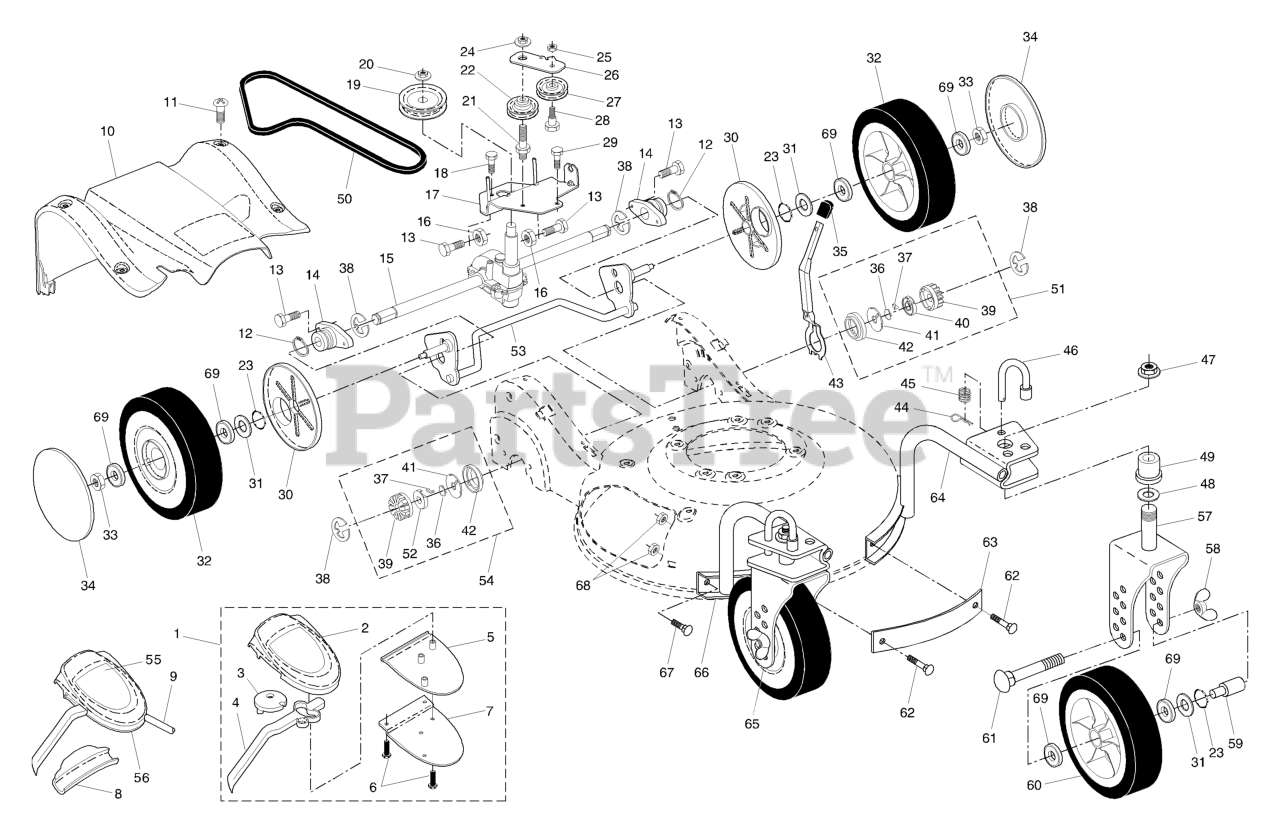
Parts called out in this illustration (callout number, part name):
1	EZ WALK CONTROL
2	COVER, DRIVE CONTROL, TOP
3	PULLEY.CAM.DRIVE.CONTROL.HV
4	LEVER, DRIVE CONTROL
5	COVER, DRIVE CONTROL BOTTOM
6	SCREW, PHILLIPS HEAD 10 X 5/8
7	BRACKET, DRIVE CONTROL
8	EZ WALK SNAP COVER PLATE
9	CABLE, DRIVE CONTROL
10	COVER ASM. DRIVE
11	SCREW
12	RETAINING RING (2 2)(3 2)
13	RP SCREW
14	BEARING.SUPPORT.ASSEM
15	TRANSMISSION.21.HI-VAC.EZ
16	NUT
17	BRACKET TRANSMISSION
19	RP PULLEY DRIVE
20	FLANGED LOCKNUT 3/8-16 ZINC
21	BOLT, IDLER
22	PULLEY ASSY
23	O-RING
24	NUT
25	NUT.CENTERLOCK.5/16-
26	BRACKET
27	IDLER PULLEY
28	SHOULDER BOLT
29	SCREW 14-20 X 5/8
30	DUST COVER, WHEEL
31	WASHER.FLAT.1/2
32	WHEEL ASM, REAR 9 X 2-1/4
33	HEX FLANGE LOCKNT
34	RB HUBCAP.3-SPOKE.SILVER
35	KNOB.SELECTOR.SPRG.H-GRY (2 2)
36	SPRING, TORSION
37	PAWL.DRIVE.21.EZ-WALK
38	E-RING 7/16 RE
39	GEAR, PINION
40	RETAINER.DRIVE.21.EZ-WALK.LT
41	DISC.DRIVE.21.EZ-WALK
42	SEAL.PINION
43	LEVER, SELECTOR, HEIGHT, REAR
44	COTTER PIN (3 2)(2 2MC)
48	WASHER.FLAT.1/2
49	RP BUSHING
50	BELT.DRIVE.EZ.WALK.HI-VAC
51	PINION ASSY, LH
52	RETAINER, DRIVE, RH
53	REAR AXLE ASSY.
54	PINION ASSY, RH
55	DECAL.DRIVE.CONTROL.HV
57	BRACKET, CASTER WHEEL, LH
58	NUT.WING.5/16-18.YELLOW
60	WHEEL ASSY, FRONT 9X2
61	CARRIAGE BOLT
63	STRAP.FRONT.CASTER.ORANGE
64	SUPPORT TUBE ASSY, LH
65	BRACKET, CASTER WHEEL, RH
66	SUPPORT TUBE ASSY, RH
68	NUT
69	BEARING.8".WHEEL
